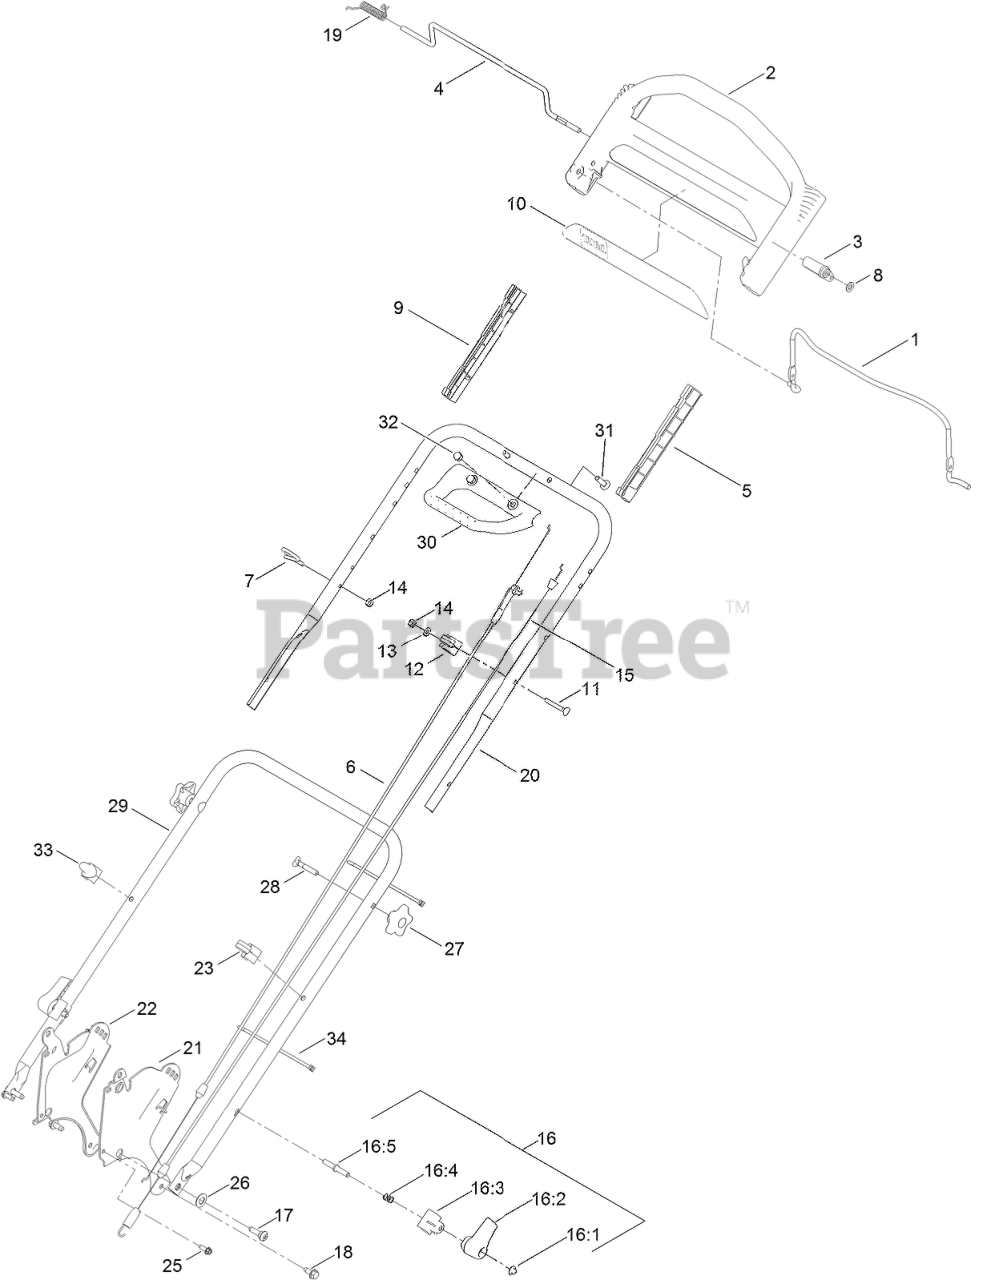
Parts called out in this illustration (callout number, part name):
1	BAIL-BRAKE
2	HANDLE-CONTROL
3	LEVER-TRACTION
4	BAR-CONTROL, TRACTION
5	GUIDE-LH
6	CABLE-BRAKE
7	GUIDE-ROPE
8	WASHER-PLAIN
9	GUIDE-RH
10	DECAL-HANDLE
11	BOLT-CARR
12	ANCHOR-CABLE
13	WASHER-FLAT
14	NUT-HEX
15	CABLE-TRACTION
16	QUICK RELEASE ASM
16:1	NUT-PUSH
16:2	LEVER
16:3	ANCHOR-SPRING
16:4	SPRING-COMPRESSION
16:5	ROD-RELEASE
17	SCREW-SHOULDER, BHTF
18	SCREW-HWHTF
19	SPRING-TORSION
20	HANDLE-UPPER
21	BRACKET-HANDLE, LH
22	BRACKET-HANDLE, RH
23	GUIDE-CABLE
25	SCREW-HWHTF
26	WASHER-SPRING, CONICAL
27	KNOB-HANDLE
28	SCREW-HANDLE
29	HANDLE-LOWER
30	HANDLE-ASSIST, TRACTION
31	BOLT-CARRIAGE
32	NUT-ACORN
33	GUIDE-ROPE, FLEXIBLE
34	TIE-CABLE
